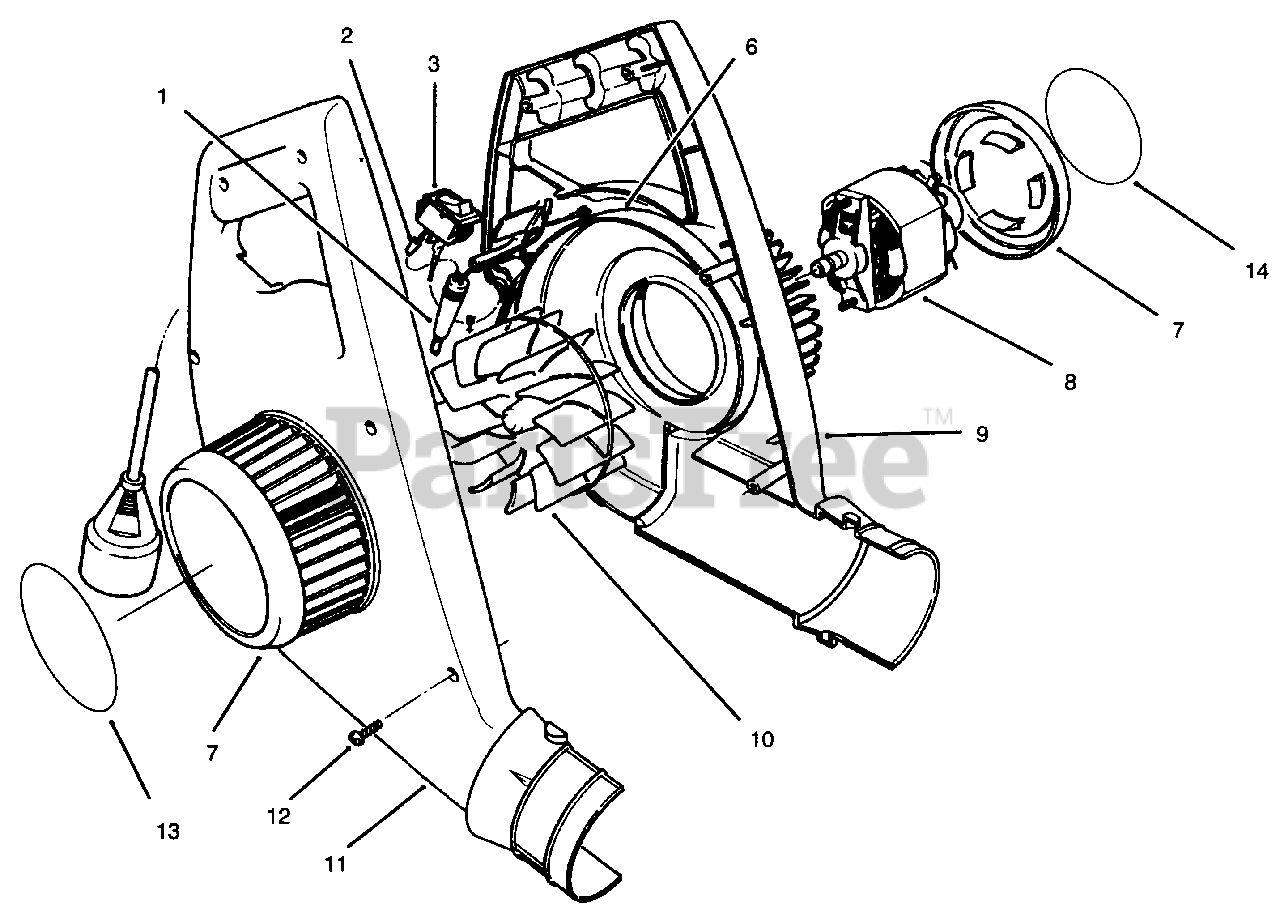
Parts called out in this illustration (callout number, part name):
1	Cord-Power Supply
2	Connector
6	Cover-Motor
7	Cover-Intake
8	Motor-120 Volt
9	Housing-L.H.
10	Impeller
11	Housing-R.H.
12	Screw-Thread Forming
13	Decal-Toro
14	Decal-UL
